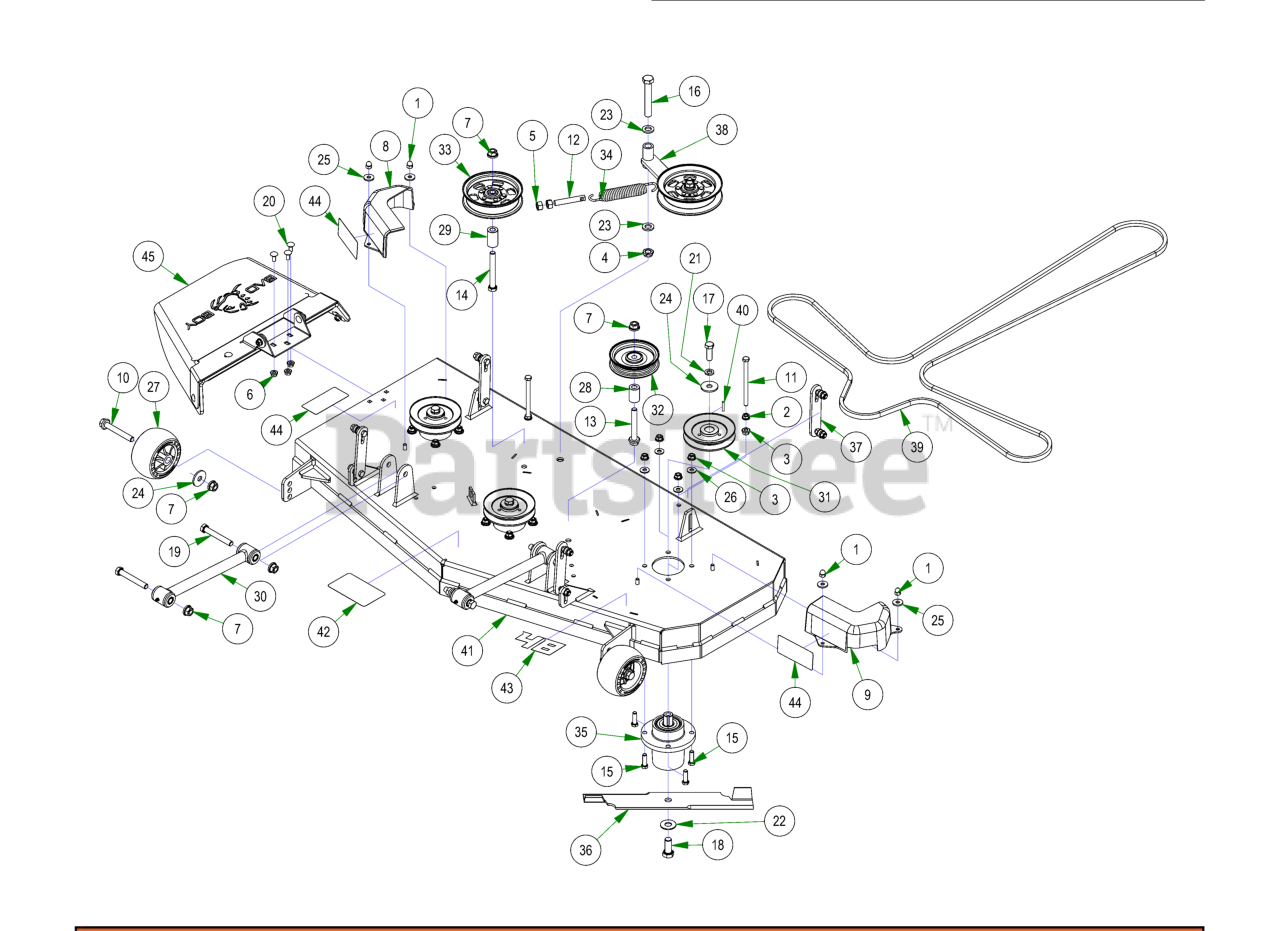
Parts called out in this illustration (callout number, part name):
1	5/16-18 ACORN NUT HIGH-CROWN ZC
2	3/8-16 HEX SERRATED FLANGE NUT HARD/ZINC
3	3/8-16 NYLON INSERT FLANGE LOCKNUT (GR.F) ZINC
4	5/8-11 NYLON INSERT JAM LOCKNUT ZINC
5	1/2-13 HEX NUT ZINC
6	5/16-18 NYLON INSERT FLANGE LOCKNUT ZINC
7	1/2-13 NYLON INSERT FLANGE LOCKNUT ZINC
8	pulley cover chute side
9	pulley cover non-chute side
10	1/2-13 X 90MM HEX FLANGE BOLT W/SHOULDER (GR.8) ZINC
11	3/8-16 X 5-1/4 HEX CAP SCREW (GR.5) ZINC
12	All Thread
13	1/2-13 X 3-1/2 HEX FLANGE BOLT (GR.8) ZINC
14	1/2-13 X 4 HEX CAP SCREW (GR.8) ZINC YELLOW
15	3/8-16 X 1-1/4 HEX CAP SCREW (GR.5) ZINC
16	5/8-11 X 4 HEX CAP SCREW (GR.8) ZINC YELLOW
17	1/2-20 X 1-1/2 HEX CAP SCREW (GR.5) ZINC
18	5/8-18 X 1-1/2 HEX CAP SCREW (GR.8) ZINC YELLOW
19	1/2-13 X 3-1/2 HEX CAP SCREW (GR.5) ZINC
20	5/16-18 x 3/4 Carriage Bolt
21	1/2 SPLIT LOCKWASHER (GR.8) ZINC/YELLOW
22	5/8 USS FLAT WASHER (1-3/4" OD) GR.8 ZINC YELLOW
23	.635 ID X 1.120 OD X .140 THICK FLAT WASHER NYLON
24	1/2 BELLEVILLE WASHER (1-5/8 OD X .140 THK) ZINC
25	.360 ID X .983 OD X .120 THICK FLAT WASHER NYLON BLACK
26	5/16 USS FLAT WASHER (7/8 OD) ZINC
27	Deck Wheel
28	.502 ID X .750 OD X 1.500 Long Spacer
29	1 3/4" Pulley Spacer
30	Hybrid Turnbuckle/Deck Locator
31	MZ Deck Pulley
32	4 3/4" Idler Pulley
33	5-3/4 Idler Pulley
34	Deck Idler Spring
35	Spindle Assembly-MZ
36	48" High Lift Fusion Blade-MZ
37	Deck Hanger Assembly
38	2017 MZ/ZT Deck Idler Assembly
39	B147 Deck Belt
40	3/16 X 1 SQ MACHINERY KEY 1018 STL ZINC
41	2023 48" x 4" Deck
42	2017 MZ Magnum 48"/42" Deck Route Decal
43	48" Deck Decal
44	Danger Decal-Spindle/Discharge
45	MZ Discharge Chute Assembly
